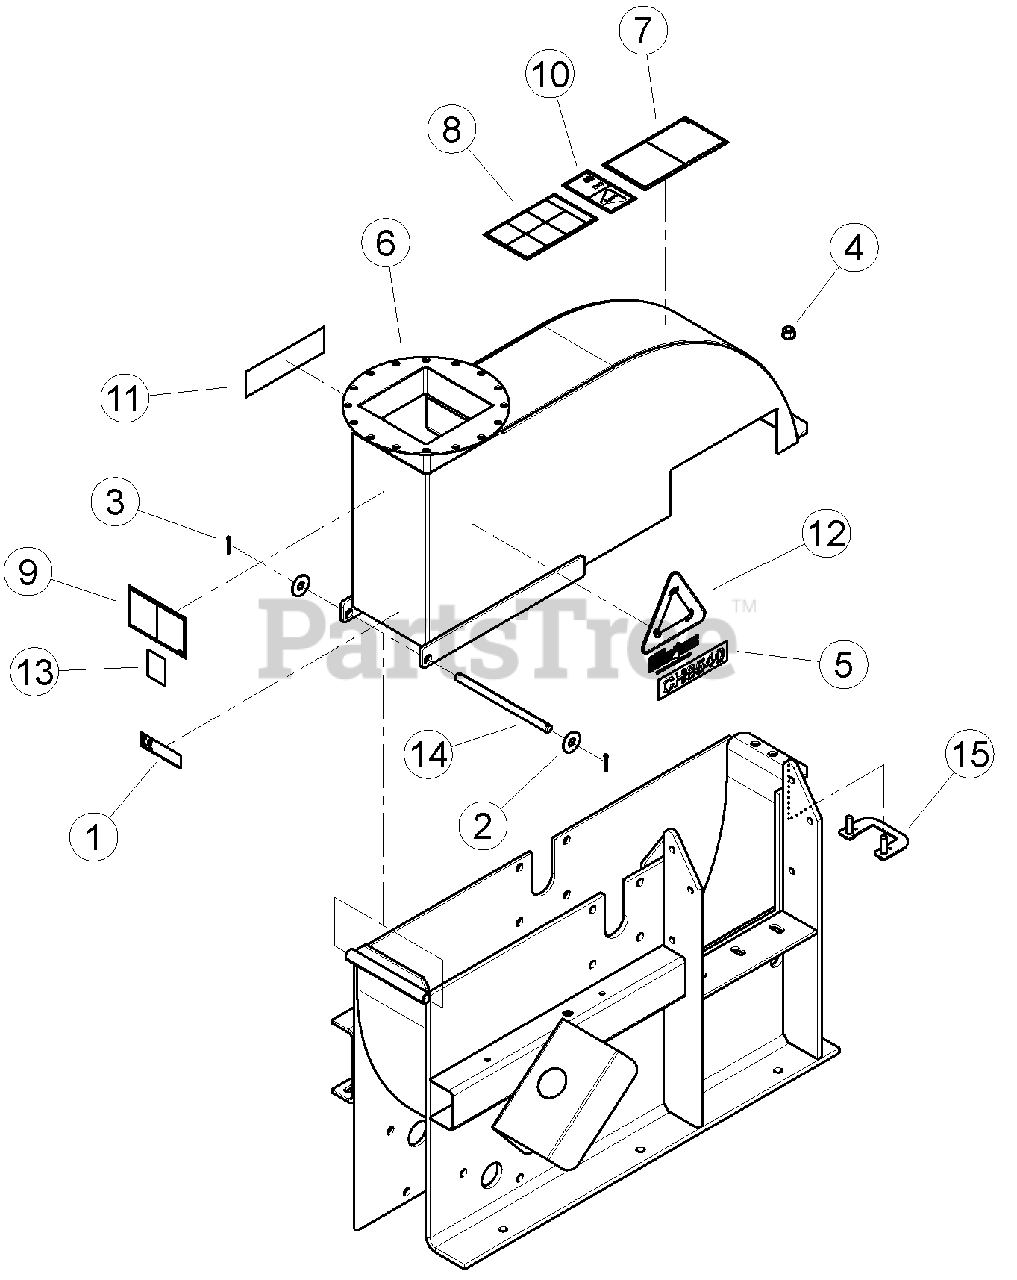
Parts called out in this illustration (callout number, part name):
1	DECAL, CH8540 INFORMATION (CE COMPLIANT ONLY)
2	WASHER, 1/2" FLAT ZP
3	PIN, 1/8 X 1.00 ZP COTTER
4	NUT, 3/8-16 NYLOCK FLANGE
5	DECAL, MODEL CH8540
6	ASSEMBLY, CHIPPER COVER W/ DECALS
7	DECAL, KNIFE ACCESS ISO
8	DECAL, OPERATING INSTRUCTIONS ISO
9	DECAL, DISCHARGE ISO
10	DECAL, MAINTENANCE ISO
11	DECAL, ECHO BEARCAT 6.82 X 1.90
12	DECAL, CHIP IT
13	DECAL, ECHO BEARCAT QR CODE
14	SHAFT, CHIPPER TOP PIVOT
15	WELDMENT, CHIPPER HOUSING ACCESS
